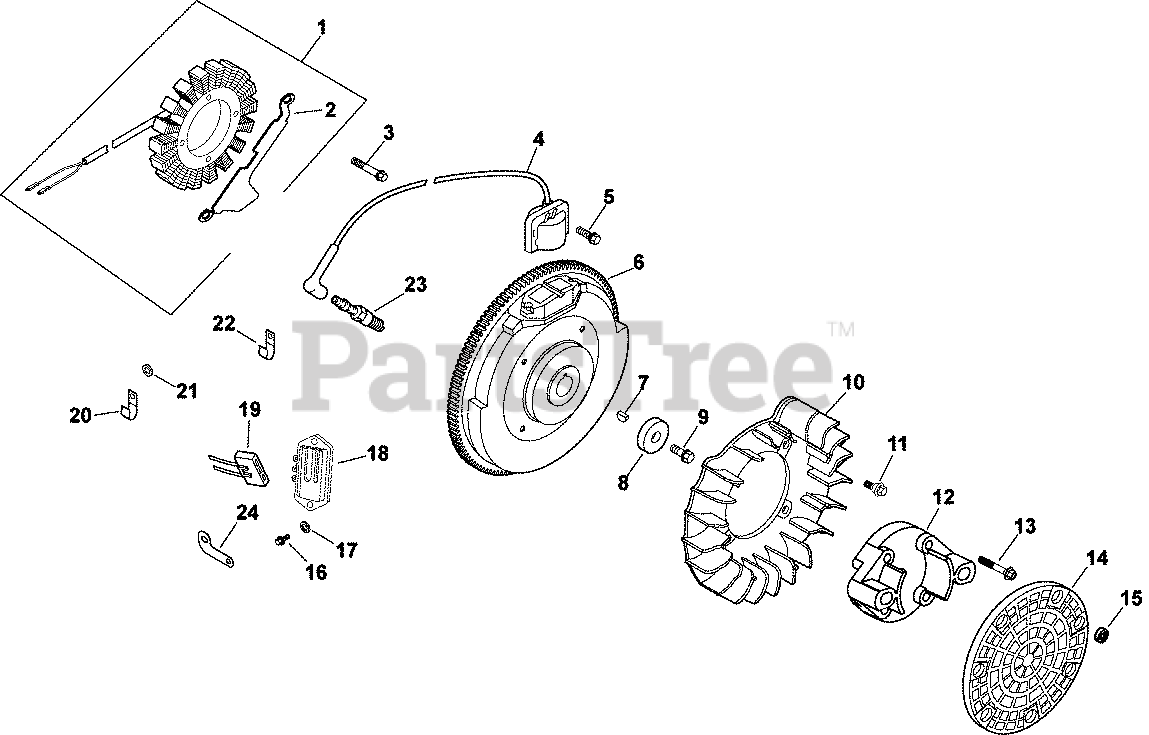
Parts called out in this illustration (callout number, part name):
1	STATOR KIT - USE 237878-S
2	BRACKET, STATOR WIRE
3	SCREW, M5X0.8X25 - (#25086402S)
4	MODULE, IGNITION-USE 24 584 45-S
5	SCREW, FLG THD FRM M5X.8X20-(#25086399S)
6	FLYWHEEL, PAINTED-USE 24 025 55-S
7	KEY, 3/16" X 5/8"
8	WASHER, FLAT 13/32"
9	SCREW, FLG M10X1.5X45 - (#25086361S)
10	FAN (KM)-USE 24 157 15-S
11	BOLT, SHOULDER
12	ADAPTER, FRONT DRIVE
13	SCREW, HEX FLANGE -USE 24 086 17-S
14	SCREEN, GRASS (#DSC)
16	SCREW, PHL HD #11-16X7/8"
17	WASHER, FLAT 3/16"
18	REG/RECT-15 AMP (KM)-USE 41 403 10-S
19	CONNECTOR, BODY (KM)-USE 25 155 41-S
20	CLIP, CABLE
21	WASHER, FLAT 1/4" (O.D. 1/2")
23	PLUG, SPARK (STD)
24	BRACKET, GROUND STRAP USE 24 518 12-S
